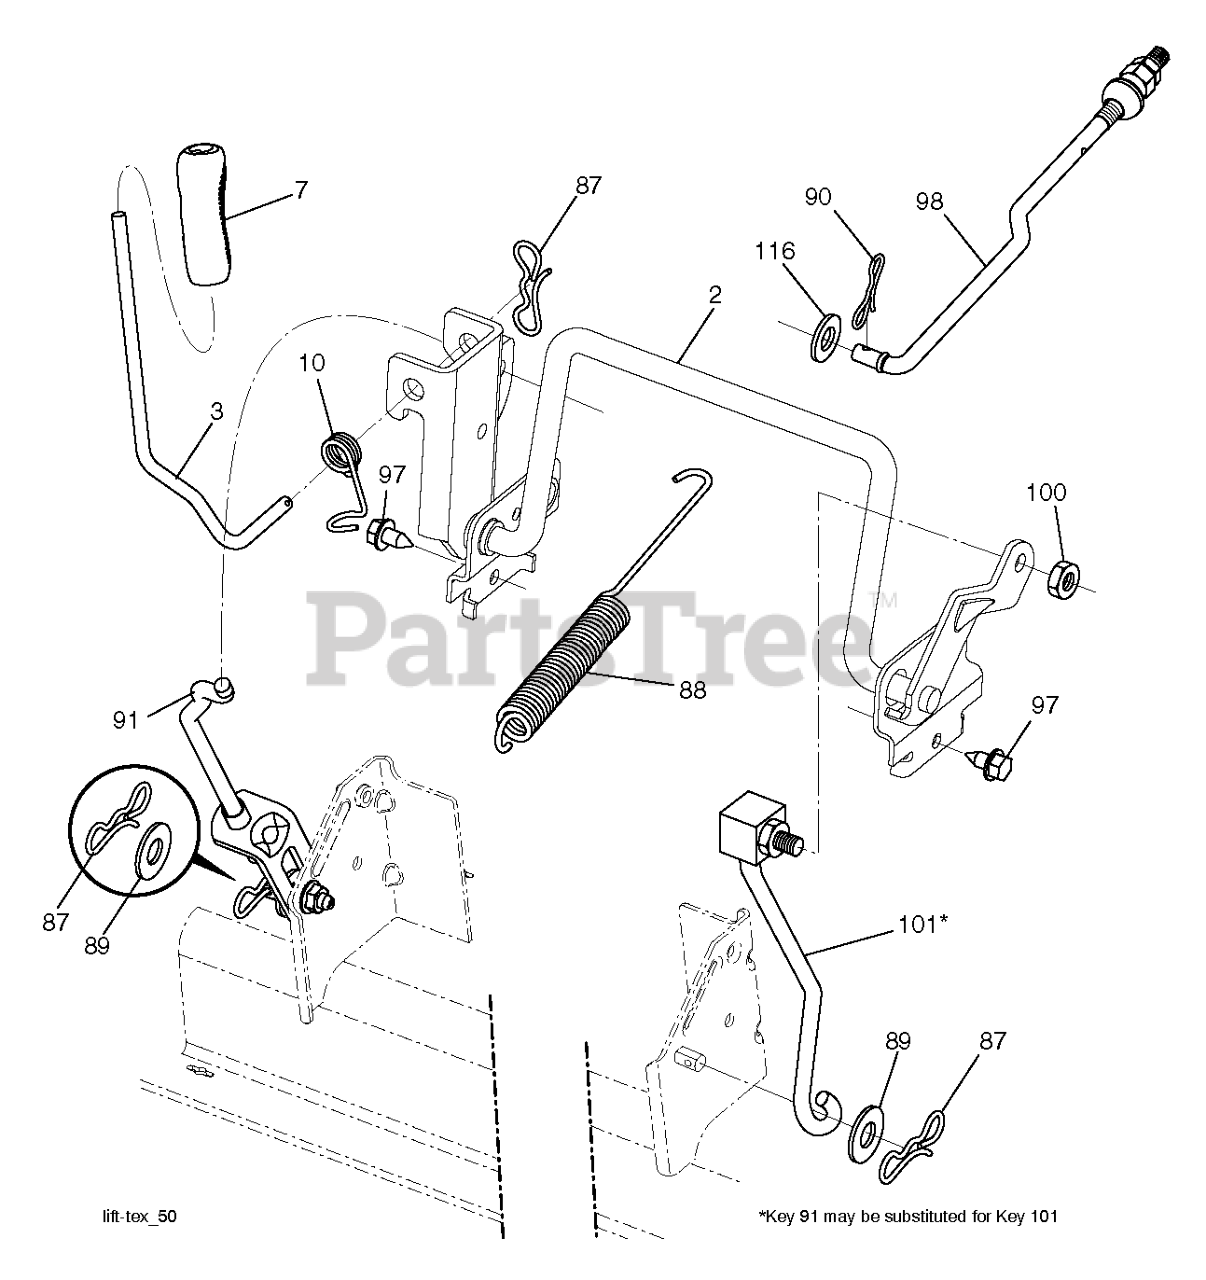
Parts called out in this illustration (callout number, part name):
2	SHAFT LIFT DECK WELD
7	GRIP.HANDLE.LIFT.PVC.BLACK
10	SPRING.TORSION.LIFT.HANDLE
87	PIN.COTTER.7/16.BOW TI.
88	SPRING SPRING LIFT ASSIST 97
89	WASHER.CLEAR.ZINC
90	PIN.COTTER.5/16.BOW TI
91	LINK ASSY LIFT.REAR 10.278
101	LINK.ASM.LIFT.FIXE.38/42/46"
